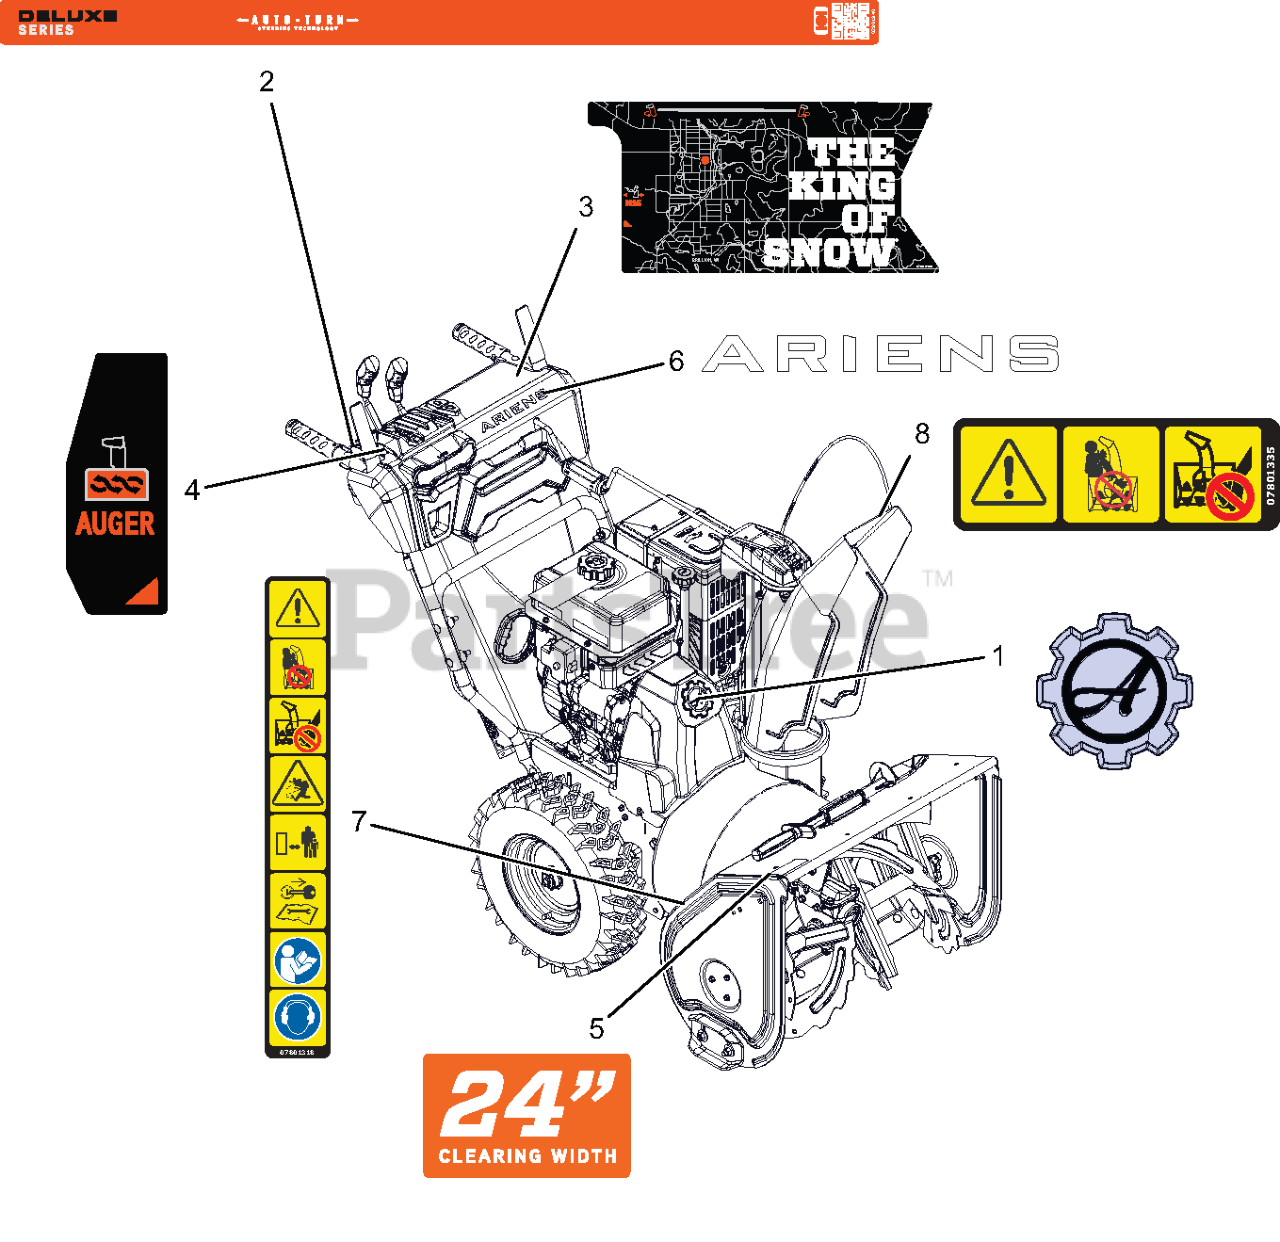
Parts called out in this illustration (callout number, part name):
1	DECAL- ARIENS GEAR BADGE
2	DECAL- DASH - DLX
3	DECAL-CONTROL-LG CHUTE ROTATE
4	DECAL- CONTROL - AUGER
5	DECAL- CLEARING - 24
6	DECAL- ARIENS - 7.46"
7	DECAL- SAFETY - DANGER
8	DECAL- DANGER
